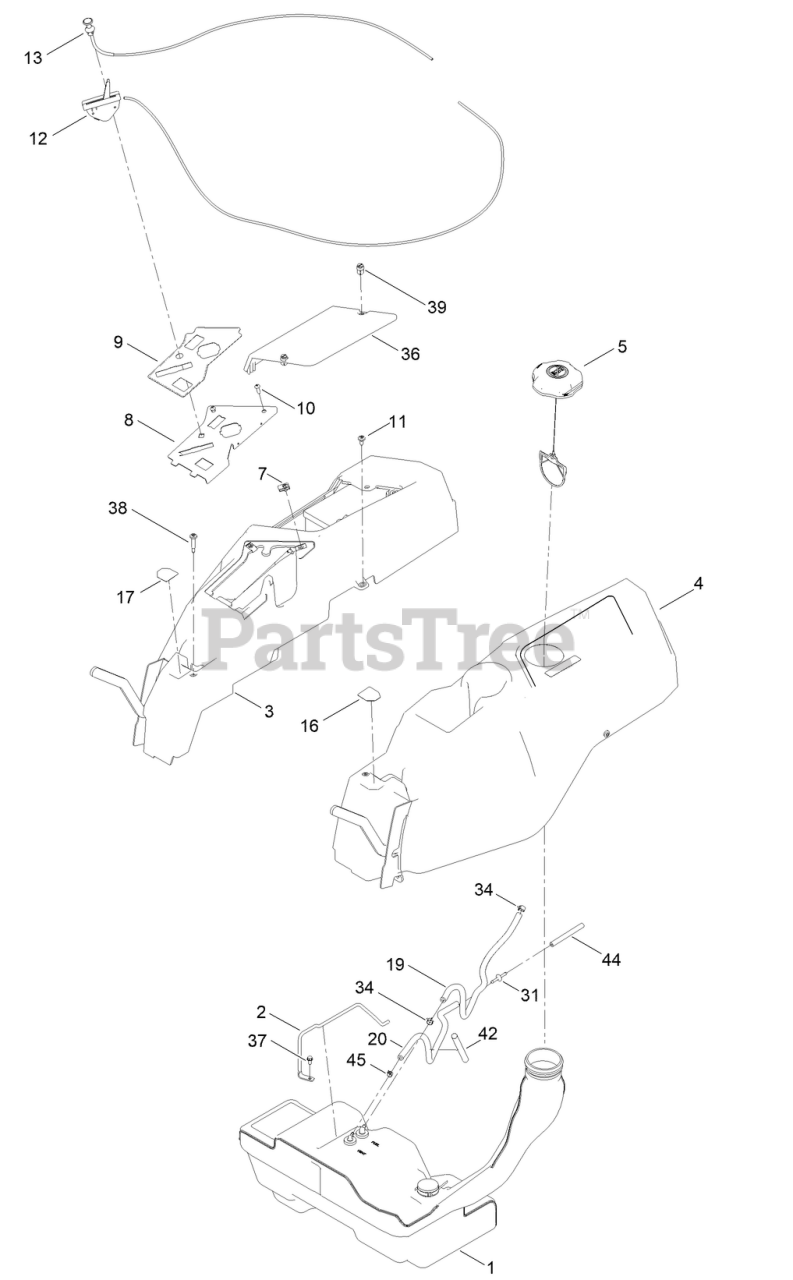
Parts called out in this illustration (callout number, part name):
1	TANK-FUEL ASM
2	ROD-HOLD DOWN
3	POD-RH
4	POD-LH
5	CAP-FUEL, RATCHETING
8	PANEL-CONTROL
9	DECAL-PANEL, CONTROL
10	SCREW-PRH
11	SCREW-SHOULDER
12	CABLE-THROTTLE
13	CABLE-CHOKE
16	DECAL-LEVER, CONTROL (LH)
17	DECAL-LEVER, CONTROL (RH)
19	HOSE-FUEL
20	HOSE-VENT
31	ADAPTER ORIFICE
34	CLAMP-HOSE
36	COVER-BATTERY
37	SCREW-HWH
38	SCREW-SHOULDER
39	FASTENER
42	SLEEVE-FUEL LINE PROTECTOR
44	HOSE-FUEL
45	CLAMP-HOSE
